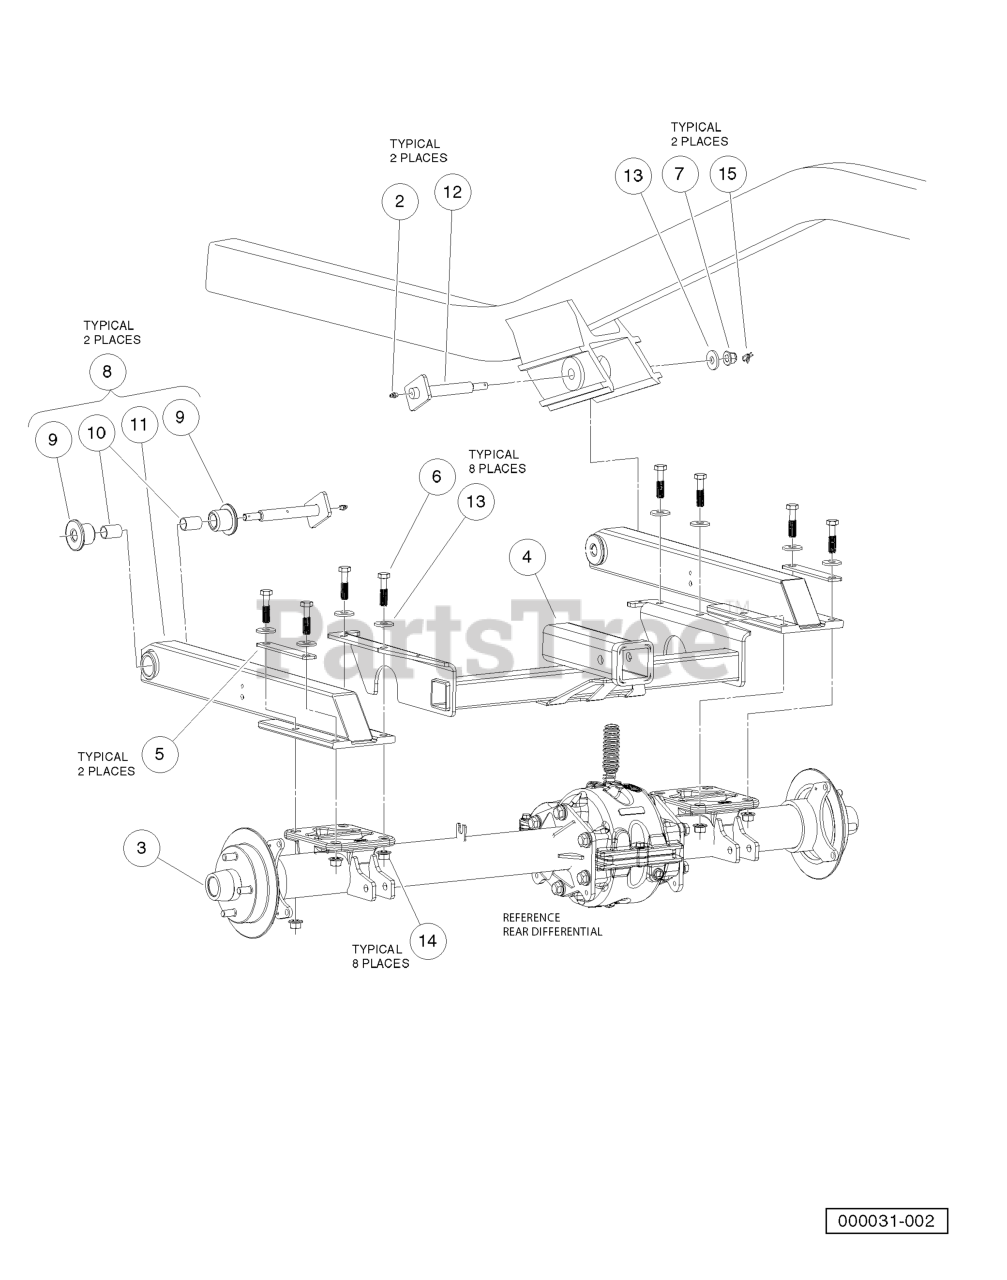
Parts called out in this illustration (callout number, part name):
1	Instl, Rear Suspension
2	FITTING, 1/4-28 THRD FRM GREAS
3	CENTER CAP, RUBBER
4	WELDMENT, RECEIVER, REAR
5	WASHER, STRIP, SWINGARM
6	BOLT FLG, M12X1.75X50
7	NUT FLG, M12X1.75, NYLON GR 10
8	Sub Asm Swingarm
9	BUSHING, PIVOT, URETHANE
10	BUSHING, TEFLON
11	SWINGARM, REAR, AWD
12	PIN, SWINGARM, WELDMENT
13	WASHER, M12 HARD REGULAR
15	COTTER-RUE RING
